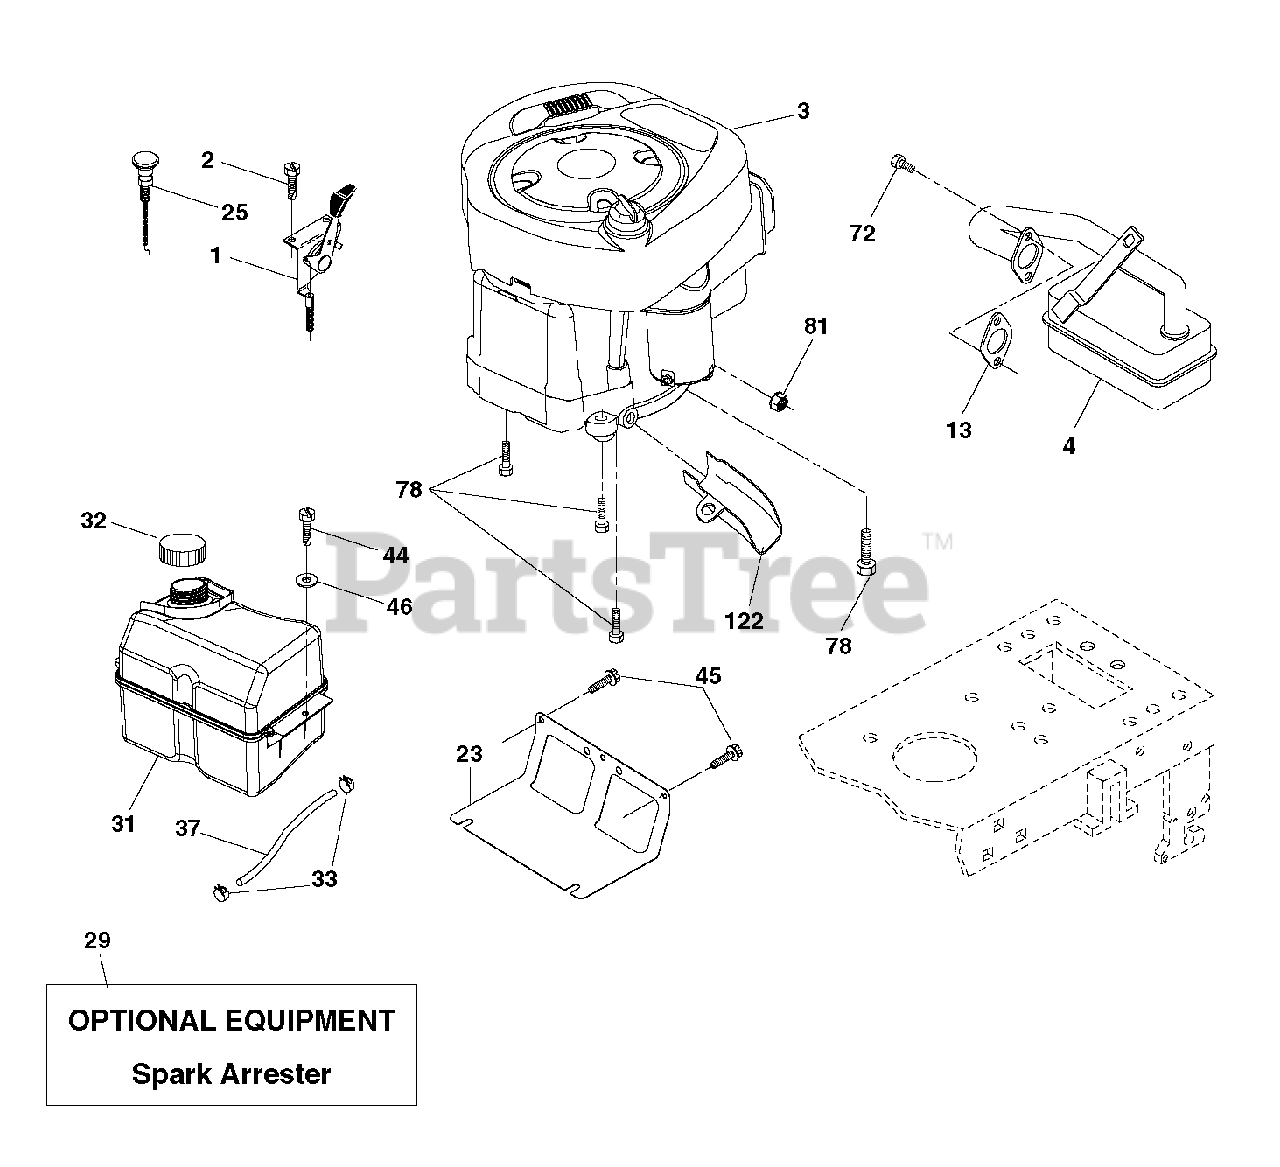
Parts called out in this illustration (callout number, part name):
1	CONTROL TH/CH FLAG
2	SCREW
13	REPL BY 532 27 22-93
23	SHEILD.BROWNING.DBR.GUARD
25	KNOB.ERGO.EXTENDED.RED (1 2)
29	ARRESTER SPARK (OPTIONAL)
32	CAP ASM.FUEL.2.25"FR.
44	SCREW HEXWSHR 1/4-20X3/4
45	SCREW, 3/8-16X3/4
72	SCREW.SOCKET HD.5/16-1
81	NUT
122	EXTENSION DRAIN OIL
